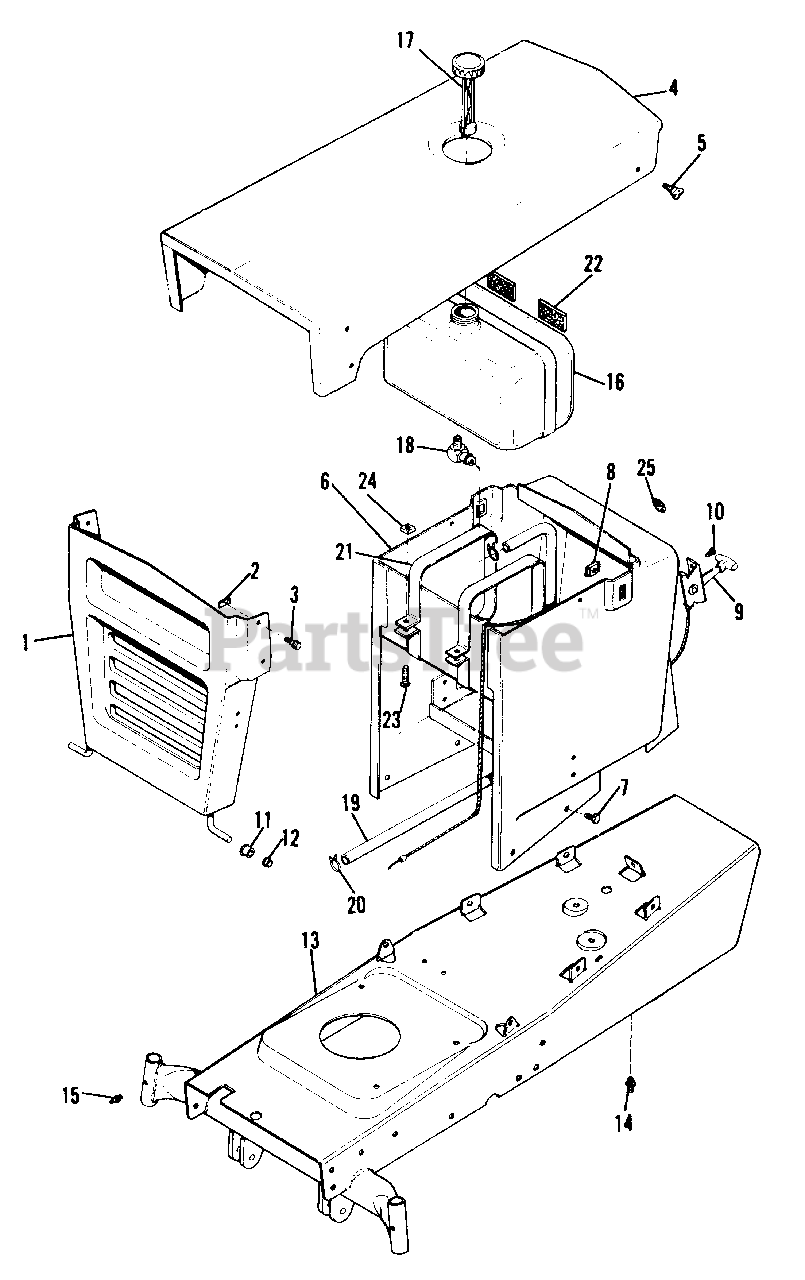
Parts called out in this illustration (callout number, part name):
1	Grille Assembly
3	Screw, Flange 1/4"-20 x 3/4 lg.
5	Screw, Thumb
6	Dash Assembly
7	Screw, Taptite, 1/4" x 3/8" lg.
8	Nut, Retainer
10	Screw, Taptite, 1/4"-20 x 3/8" lg.
12	Fastener, Pushout
13	Frame Assembly
14	Fitting, Grease
15	Fitting, Grease
16	Tank, Fuel
17	Cap, Fuel Tank
18	Elbow, 90ø
19	Hose, Fuel
20	Clamp, Hose
21	Strap, Tank
22	Gasket, Felt
23	Screw, Mach. 1/4"-20 x 1-1/2" lg.
24	Nut, Square, 1/4"-20
25	Button, Plug
